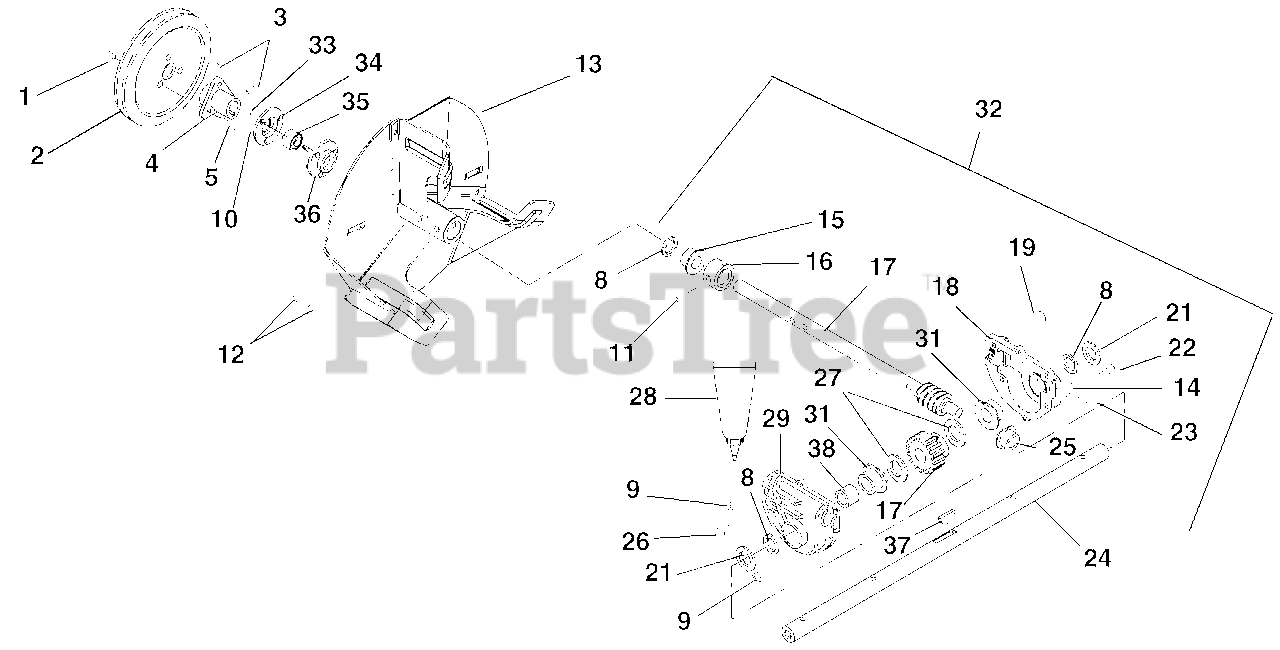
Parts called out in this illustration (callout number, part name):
1	@NUT-SPNLK-FLG .312-18 YWZC
2	PLY-V 8.50 X 1.25 3BLT
3	SCR-SET .31-18X.38 SKHCUPDL
4	HUB ASSEMBLY
5	BLT-SERRDHD SL .31-18X.75 YZ
8	SEAL-OIL .750X1.375X.250
9	@NUT-SPNLK-FLG .25-20 YWZC
10	KEY-WDRF .188X.875X.375 SAE11
11	PIN-GRV .188X1.25 TP A
12	PIN-ROLL .250X1.25
13	IMPELLER - .75 ID X 10" OD
14	WSHR-FIBER .437X.656X.032
15	BSHG-FLG .750X1.000X.750X1.250
16	THRUST COLLAR
17	SHAFT AND WORM GEAR ASSEMBLY
18	CASE, GEAR-LH-LARGE BORE-ALUM.
19	@BLT-RDHDSQNK .25-20X1.25 G5YZ
21	@WSHR-FL-STL.812X1.50X.135YWZC
22	@BLT-RDHDSQNK .25-20X1.00 G5YZ
23	@SCR-TAP .38-16X.50 HWH TR YWZ
24	SHAFT, RAKE - 20"
25	BSHG-FLG .502X1X.750
26	SCR-TAP 10-24X.75 HWH TR YWZC
27	WSHR-HDND-THRST .755X1.40X.062
28	LOCTITE 518 GASKET--6ML TUBE
29	CASE, GEAR-RH-LARGE BORE-ALUM.
31	BSHG-FLG .753X1.127X.500X1.501
32	GEAR CASE - 20" - ALUMINUM
33	@NUT-LK-CTR .25-20 YWZC
34	BEARING FLANGE
35	BRG-BALL .750X1.750X.50
36	BEARING FLANGE
37	KEY-WDRF .188X.625X.25 SAE 61
38	BSHG-SLV .755X1.500X.442
